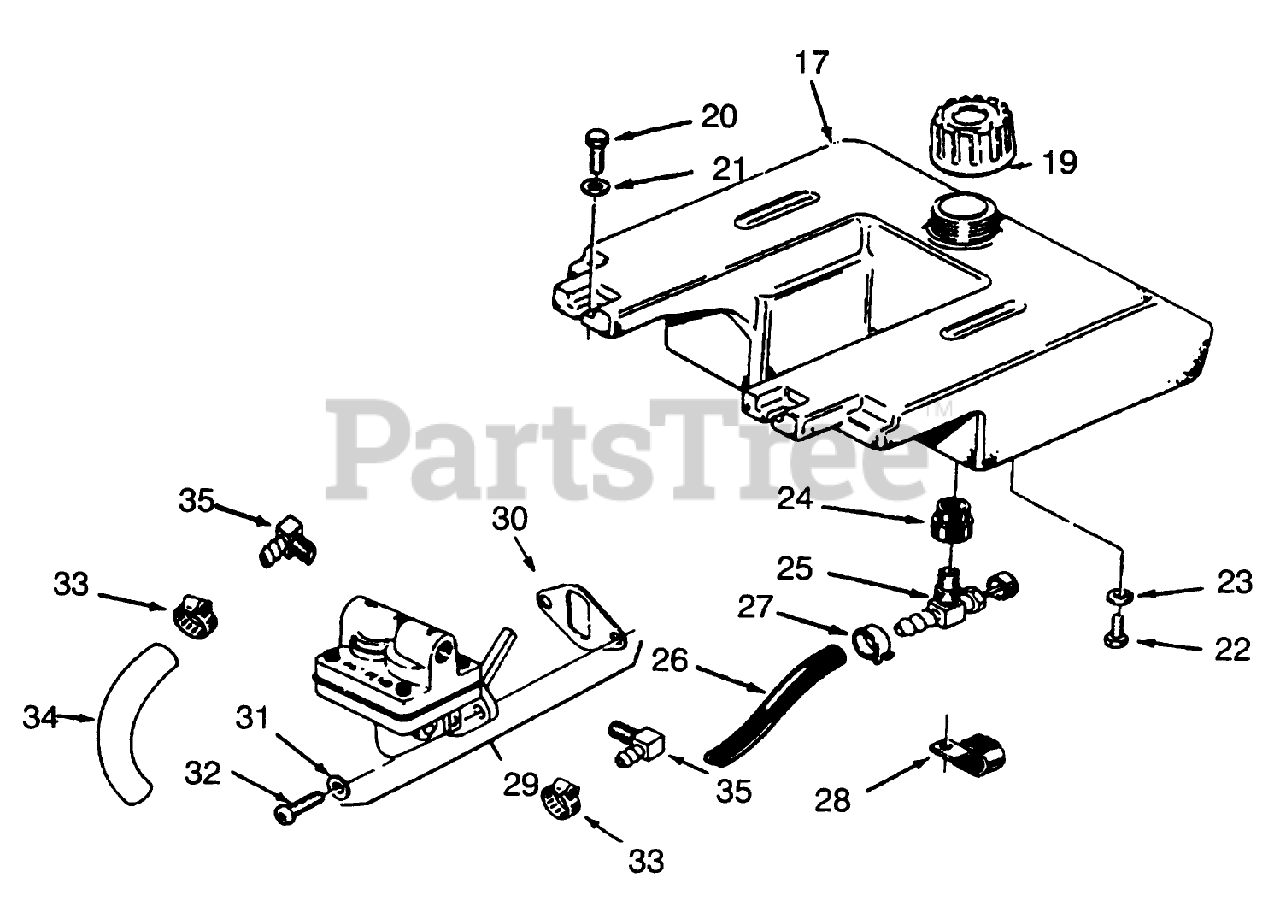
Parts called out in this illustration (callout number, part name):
17	TANK-FUEL
18	GAS CAP ASM
21	WASHER-FLAT
22	SCREW-HH
23	WASHER-LOCK
25	VALVE-FUEL
29	KOHLER 47-559-08
30	VNDR #25-041-09
31	KOHLER X-25-63
32	KOHLER X-174-2
33	KOHLER X-426-9
34	VNDR #25-353-08
35	KOHLER 25-155-02
